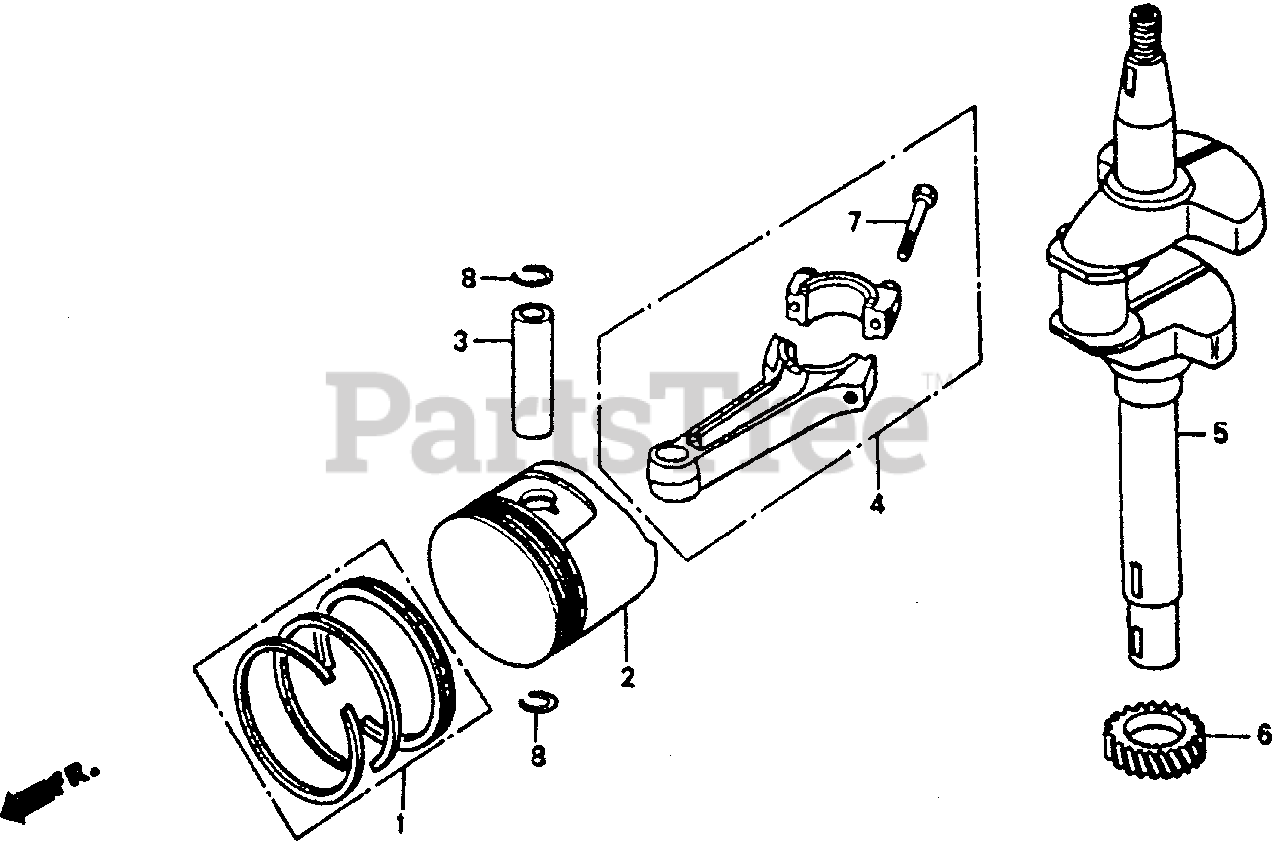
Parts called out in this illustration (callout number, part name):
1	RING SET, PISTON (STD) (TEIKOKU)
1	RING SET, PISTON (STD) (NIPPON)
1	RING SET, PISTON (0.25) (TEIKOKU)
1	RING SET, PISTON (OVER SIZE) (0.25) (TEIKOKU) Use up to Engine SN 4733210.
1	RING SET, PISTON (0.50) (TEIKOKU)
1	RING SET, PISTON (0.50) (NIPPON)
1	RING SET, PISTON (OVER SIZE) (0.50) (TEIKOKU) Use up to Engine SN 4733210.
1	RING SET, PISTON (0.75) (TEIKOKU)
1	RING SET, PISTON (0.75) (NIPPON)
1	RING SET, PISTON (OVER SIZE) (0.75) (TEIKOKU) Use up to Engine SN 4733210.
1	RING SET, PISTON (0.75) (NIPPON) (NOT AVAILABLE)
2	PISTON (STD)
2	PISTON (0.25)
2	PISTON (OS 0.50)
2	PISTON (0.75)
3	PIN, PISTON
4	ROD ASSY., CONNECTING
4	ROD ASSY., CONNECTING (0.25 LOWER SIZE) (NOT AVAILABLE)
5	CRANKSHAFT
6	GEAR, TIMING
7	BOLT, CONNECTING ROD
8	CLIP, PISTON PIN (18MM)
